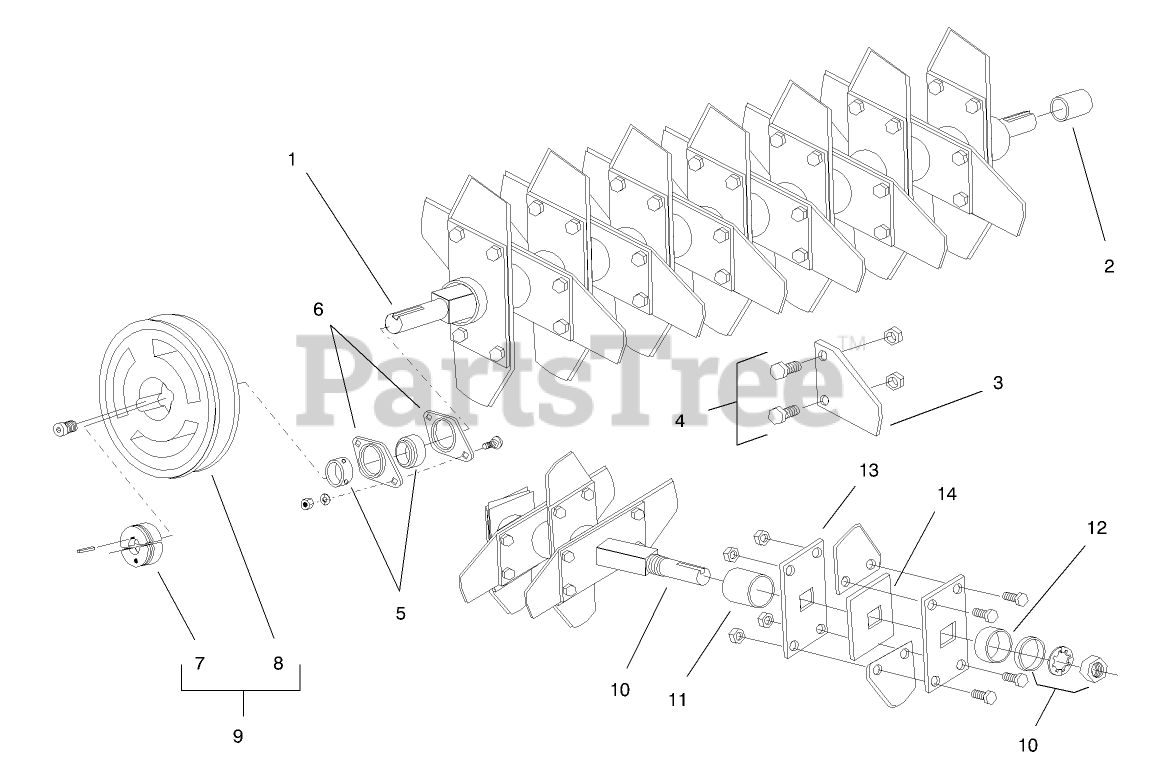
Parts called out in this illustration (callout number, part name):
1	ASSEMBLY - REEL
3	BLADE SET
4	KIT - BOLT
5	BEARING
6	KIT - STAMPING
7	BUSHING
8	V-PULLEY
9	V-PULLEY
10	SHAFT
11	SPACER
12	END RING
13	PLATE
14	PLATE
